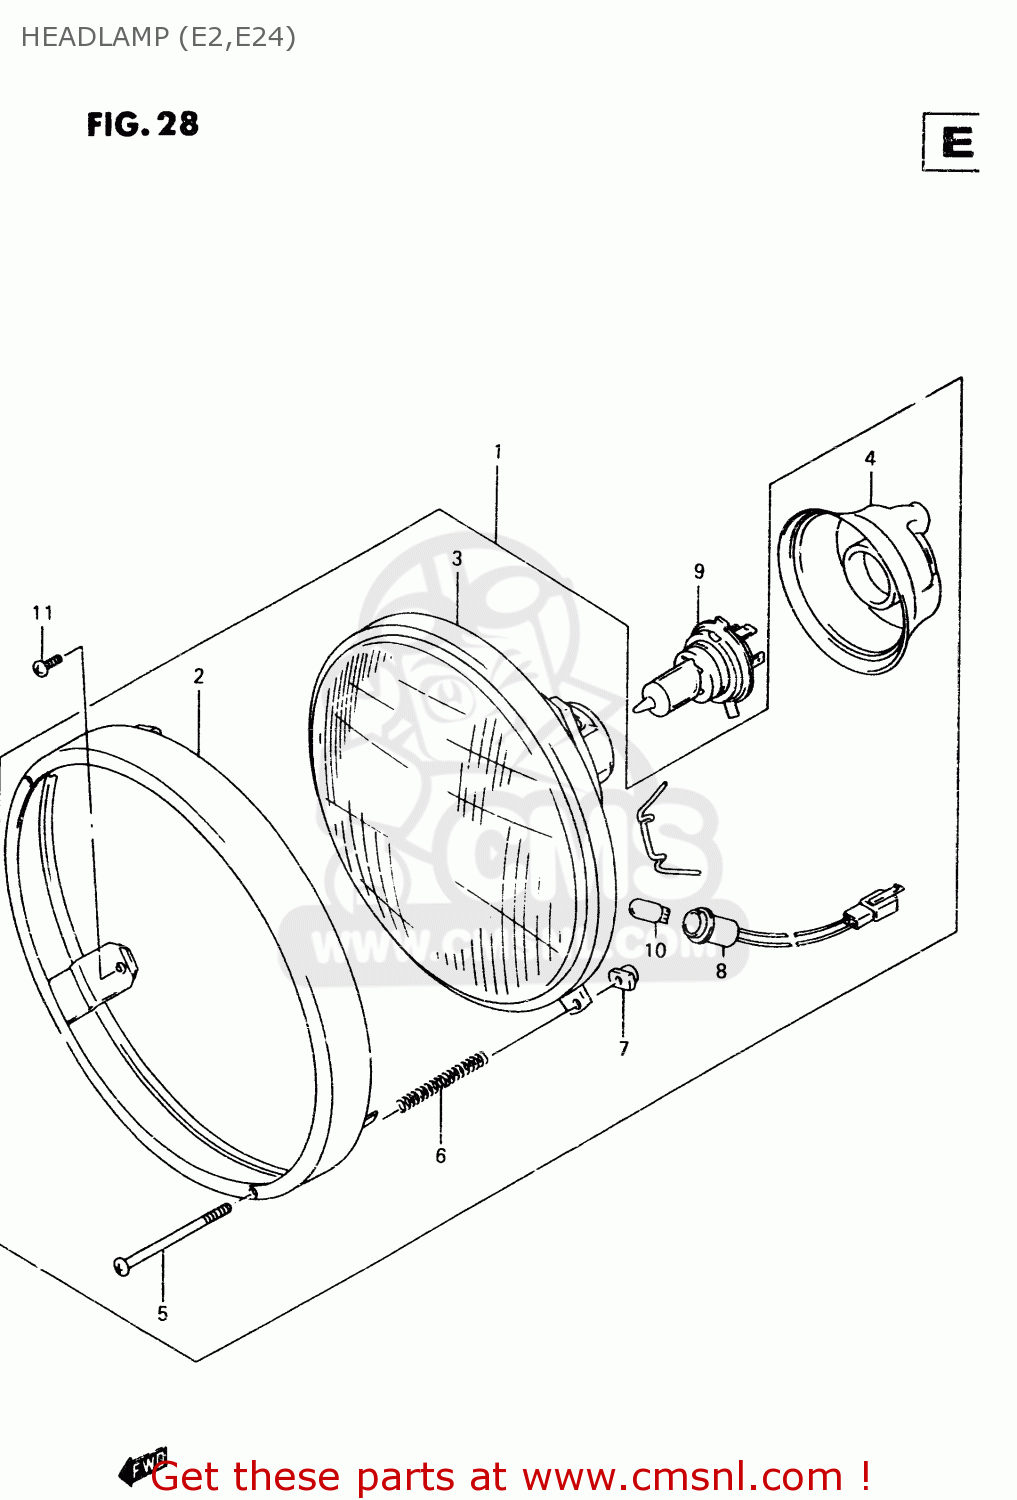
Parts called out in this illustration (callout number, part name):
1	HEADLAMP ASSY
2	RIM ASSY
3	LAMP UNIT
4	COVER,SOCKET
5	SCREW
6	SPRING,ADJUSTING
7	NUT
8	SOCKET,PARKING LAMP
9	BULB(12V60/55W,H4)
10	BULB(12V4W)
11	SCREW(5X12)
